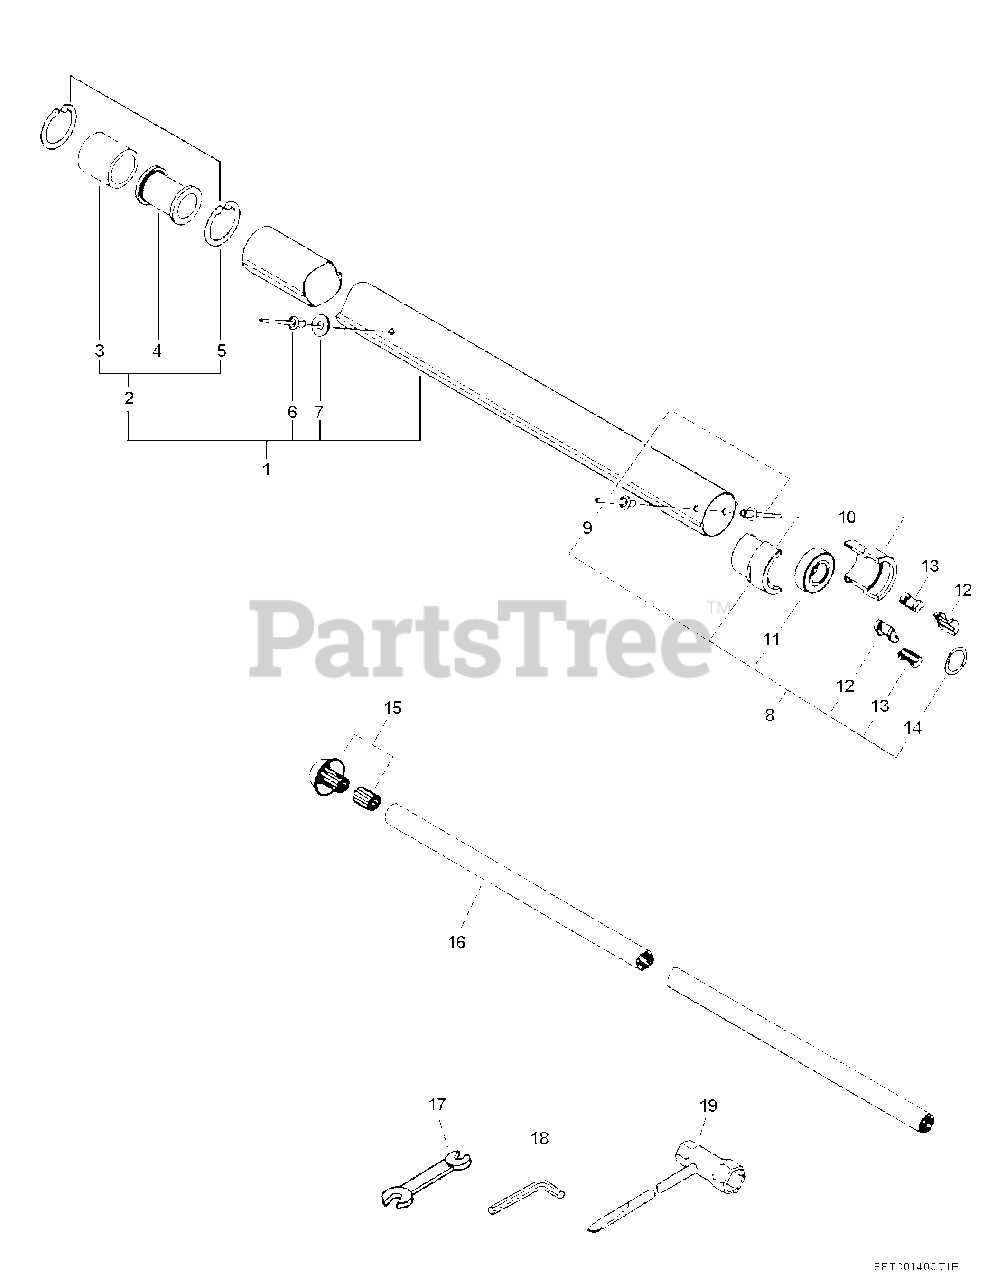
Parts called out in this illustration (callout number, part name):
1	MAIN PIPE ASSY - BLACK
2	DRIVESHAFT GUIDE ASSY
3	PAD, FOAM
4	GUIDE, DRIVESHAFT
5	RING, RETAINING
7	WASHER - 5
8	BEARING HOLDER KIT
10	BEARING HOLDER KIT
11	BEARING, BALL - 6002
12	HOLDER, INNER BEARING - LARGE
13	HOLDER, INNER BEARING - SMALL
14	WASHER - SPRING
15	ADAPTER, DRIVESHAFT - UPPER
16	DRIVESHAFT - UPPER
17	SPANNER - 8X10mm
18	HEX KEY - 3mm
19	T-WRENCH
